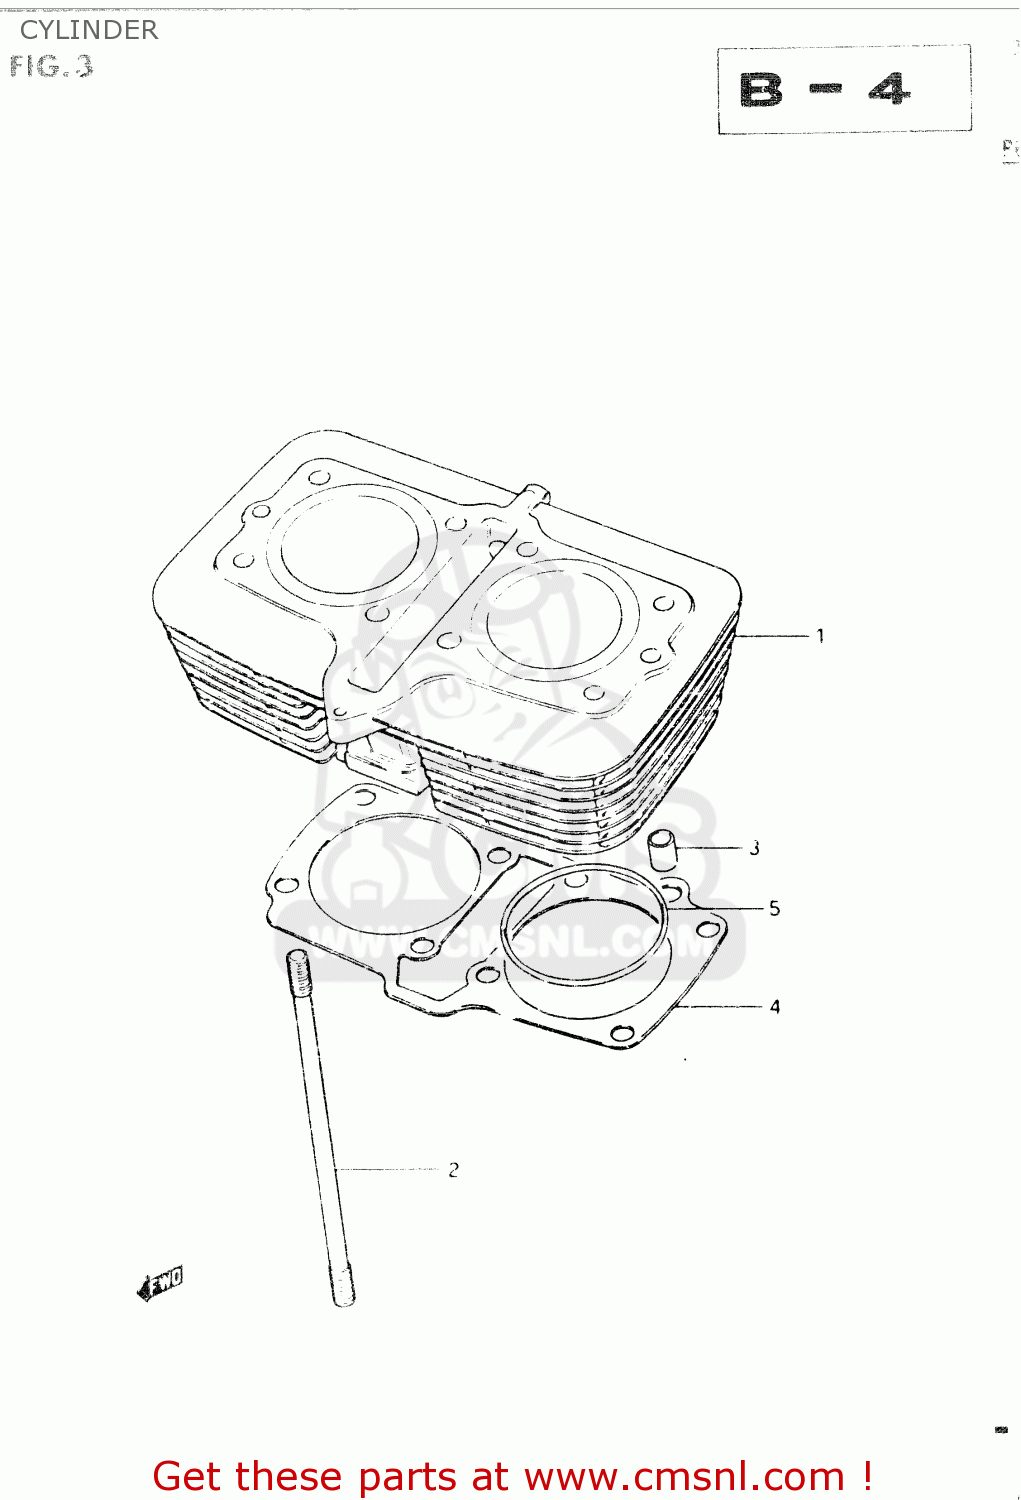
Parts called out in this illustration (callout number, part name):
1	CYLINDER
2	STUD
3	PIN
4	GASKET (T:1.2) (MCA)
5	O RING(D:2,ID:70)
